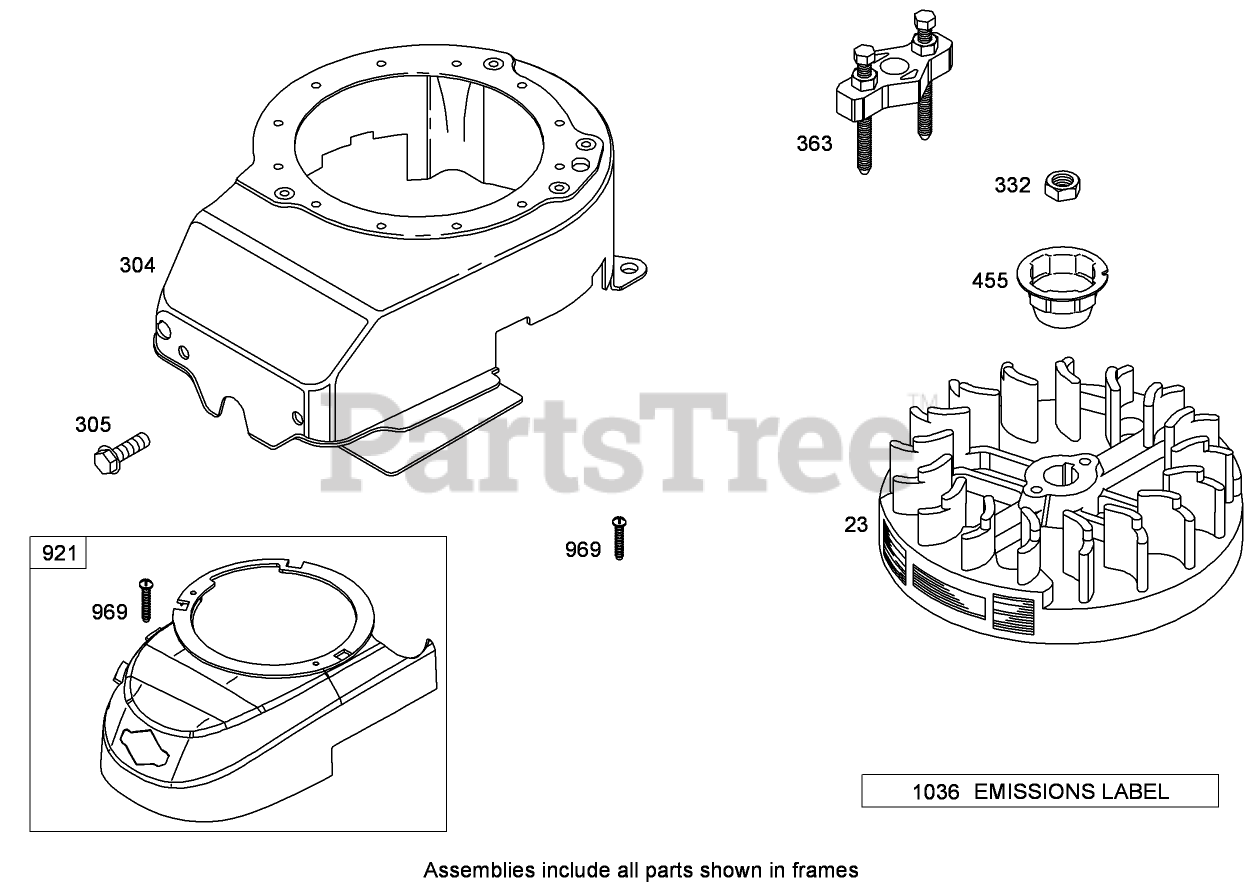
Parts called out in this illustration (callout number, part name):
23	Flywheel
304	Housing-Blower
305	Screw
332	Nut
363	Puller-Flywheel
455	Gasket-Passage, Breather
921	Cover-Housing, Blower
969	Screw
1036	Loose Parts Package
